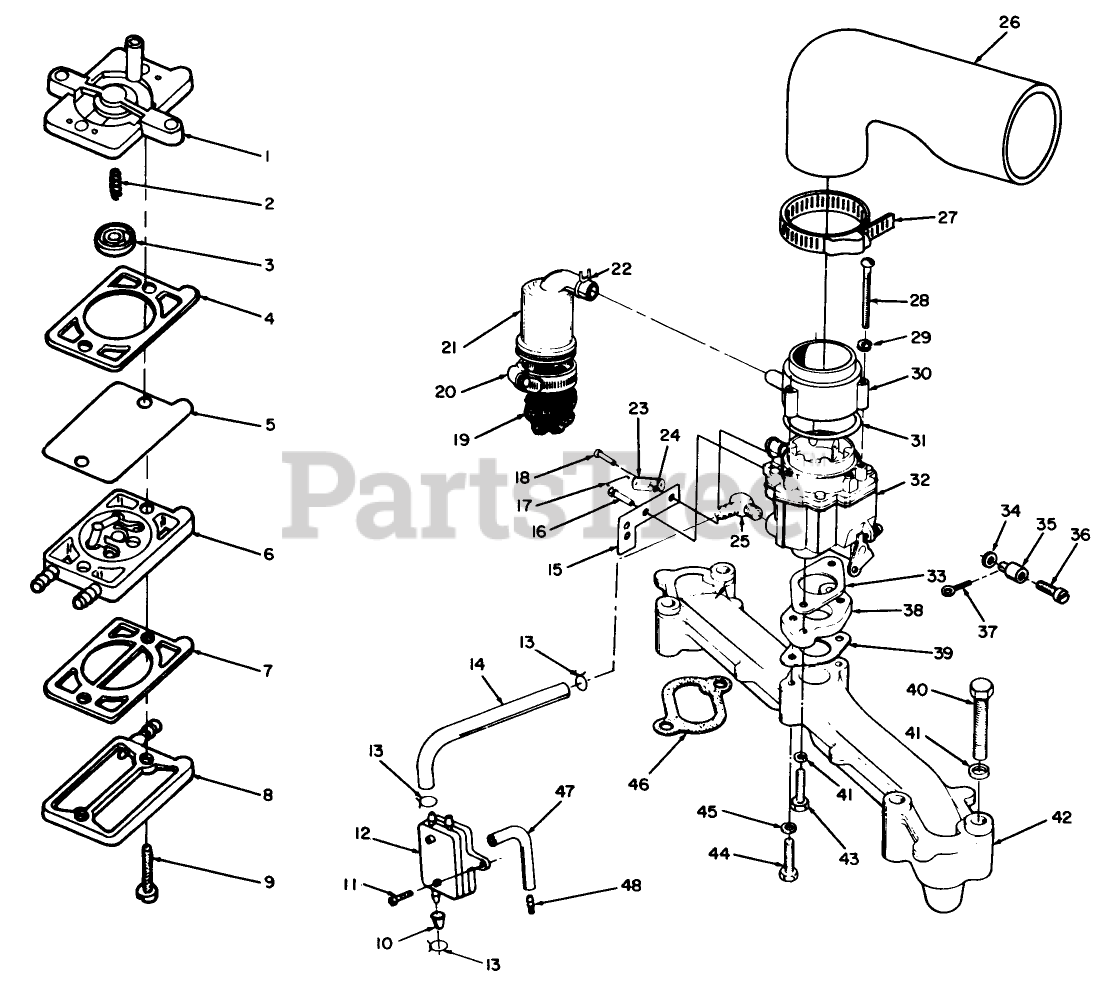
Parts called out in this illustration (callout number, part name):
1	Base, Pump
2	Spring, Fuel Pump
3	Plate, Drive-Fuel Pump
4	Gasket-Pump Cover
5	Diaphragm-Fuel Pump
6	Valve Assembly, Reed-Fuel Pump (Includes Cap Clamp)
7	Gasket-Cover to Valve Assy.
8	Cover-Pump
9	Screw-Pump Cover to Body
10	Cap, Fuel Outlet
11	Screw, Tapping Pan Hd.
12	Pump, Fuel-Vacuum Pluse (Incl. Ref. #1-9)
13	Clamp, Hose
14	Hose, Fuel (13")
15	Bracket, Cable Choke
16	Screw, Cap Hex Washer Hd.
17	Link, Choke
18	Screw, Shoulder
19	Filter, Breather Tube
20	Clamp, Breather Tube
21	Tube, Crankcase Breather
22	Camp, Hose
23	Swivel, Choke
24	Washer, Lock Internal Tooth
25	Elbow-Hose
26	Elbow Air Inlet
27	Clamp Hose
28	Screw-Machine Round Hd.
29	Washer-Lock
30	Adapter, Air Cleaner
31	Seal, O-Ring
32	Carburetor, Complete (Incl. Ref. #32)
33	Gasket Carburetor Mounting
34	Washer
35	Swivel
36	Screw
37	Cotter Pin
38	Adapter, Carburetor
39	Gasket, Adapter to Manifold
40	Screw, Cap-Hex Head
41	Washer, Lock-Spring
42	Manifold, Intake
43	Screw Cap-Hex Hd.
44	Screw Cap-Hex Hd.
45	Washer, Lock
46	Gasket, Manifold to Block
47	Hose, Fuel Pump Vacuum
48	Tube, Vacuum Port
